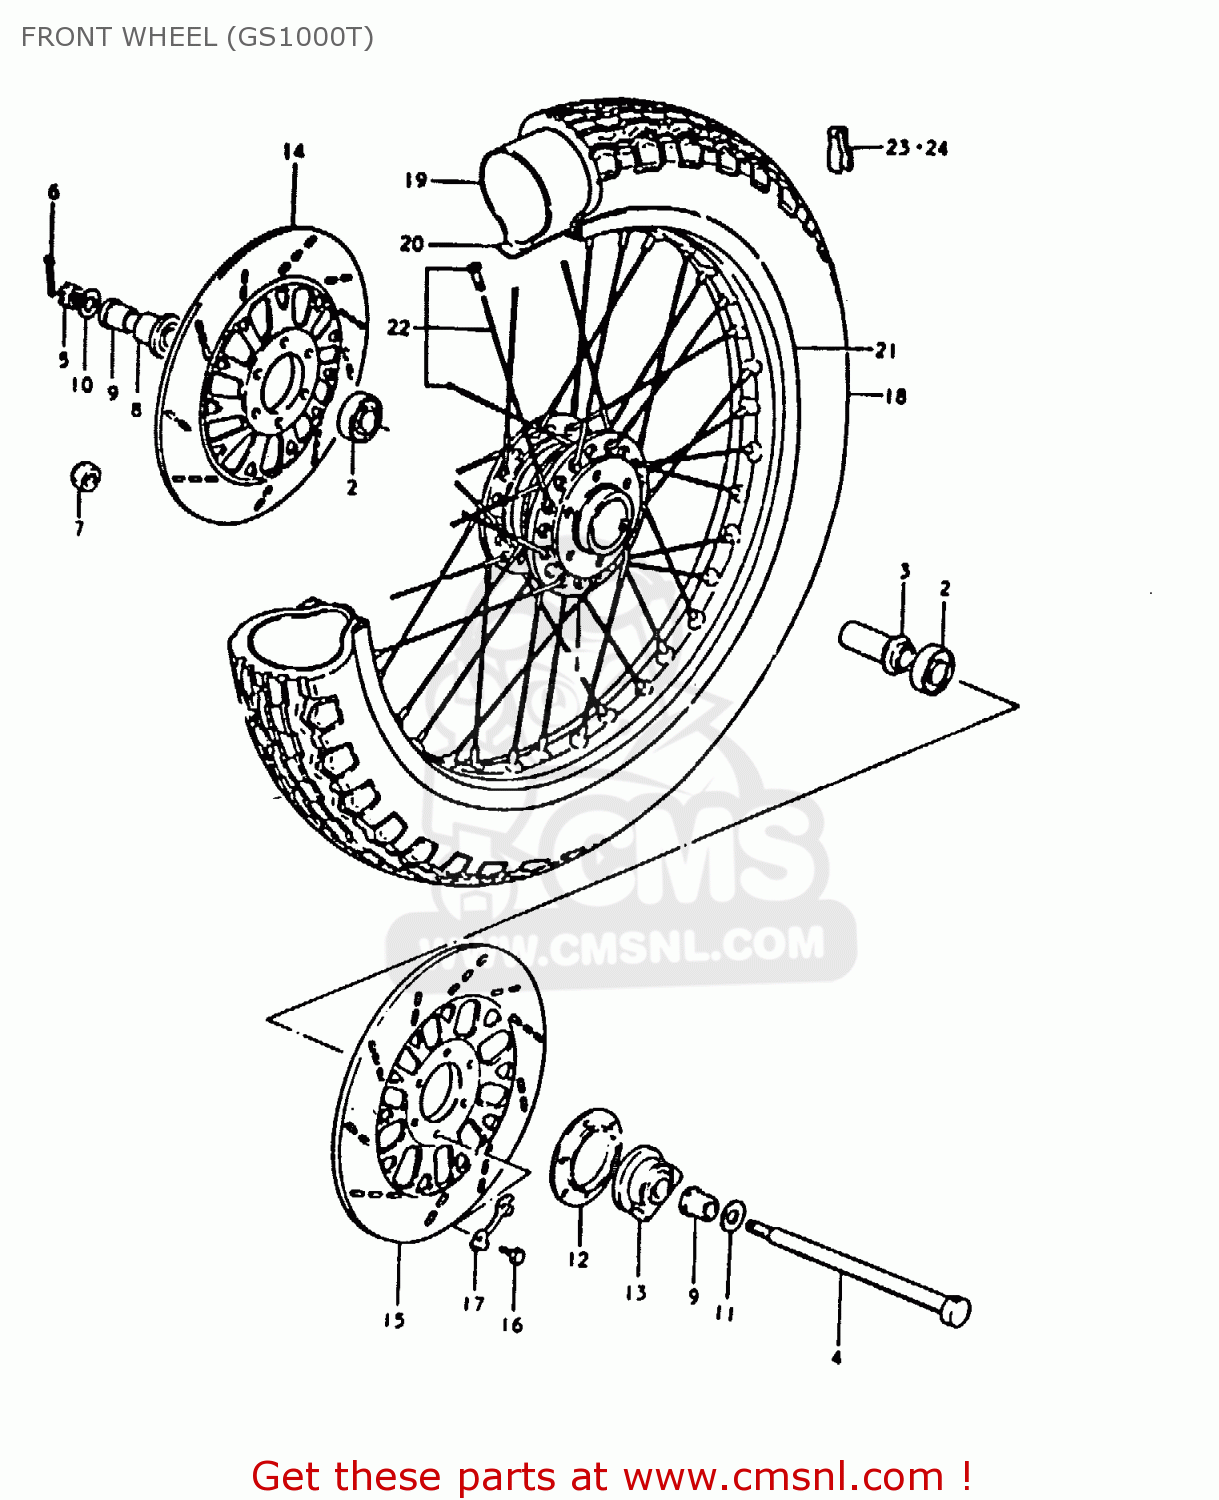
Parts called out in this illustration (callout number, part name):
1	DRUM,FRONT HUB
2	BEARING
3	SPACER,FR HUB BEARING
4	AXLE,FR
5	NUT 12MM
6	COTTER PIN
8	SPACER,FR AXLE,R
9	SPACER,FR AXLE,L
10	WASHER
12	DUST SEAL,SPEEDOMETER GEAR BOX
13	BOX ASSEMBLY,SPEEDOMETER GEAR
14	DISC,FR BRAKE,R
15	DISC,FR BRAKE,L
16	BOLT(8X25)
17	WASHER
18	TIRE,FRONT
19	TUBE,INNER
20	PROTECTOR,WHL INR TUBE
21	RIM,FRONT WHEEL
22	SPOKE SET,FRONT
23	BALANCER,WHEEL (B)
24	BALANCER,WHEEL (30G)
